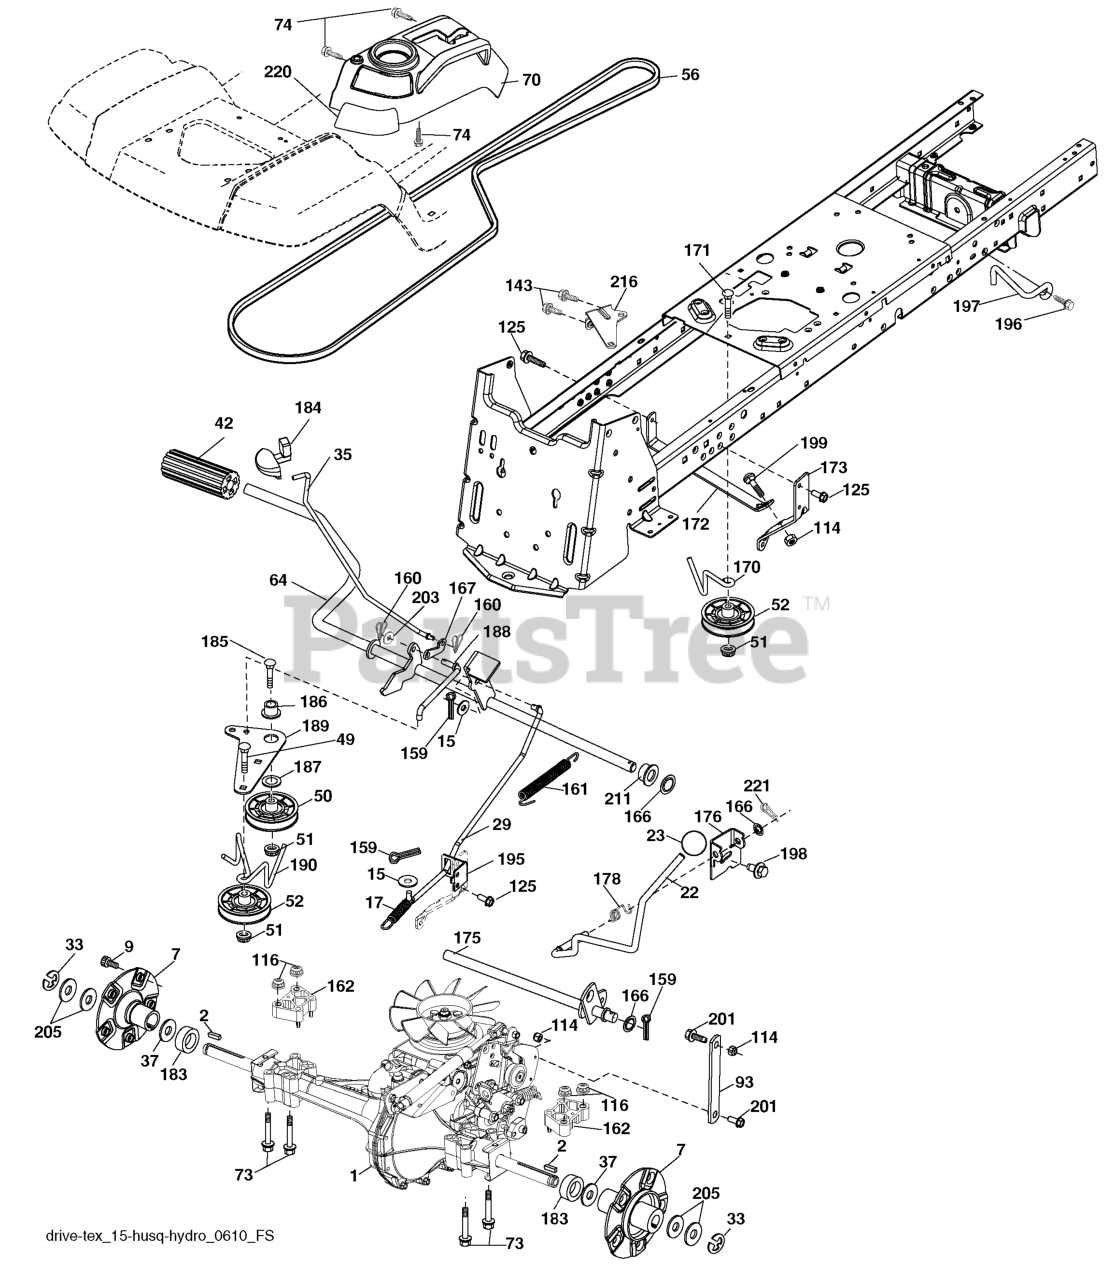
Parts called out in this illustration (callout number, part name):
2	KEY.SQUARE.187X2.500
7	HUB.ASM.WHEEL.REAR.22"
9	HUB BOLT
15	WASHER
17	SPRING.BRAKE.HG3000/3500
22	ROD.SHIFT.FENDER.STGT.
23	KNOB.DELUXE.(PISTOL.GRIP).BLAC
29	ROD.BRAKE.0610.PEDAL.CONTROL
35	ROD.BRAKE.PARKING.GT.H
42	PEDAL COVER T
49	BOLT
50	IDLER.FLAT.910.OFFSET
51	NUT LOCK FLG 3/8-16 UNC
52	IDLER.V-GROOVE.910.OFFSET
64	SHAFT.ASM.PEDAL.BRAKE.
70	RP CONSOLE.ASM.HYDO.HUSQ.
73	BOLT.HEX.FLNG.5/16-18X3.75
74	SCREW.HI-LO.CONSOLE
93	LINK.SHIFT.T/A.0610.TE
114	NUT.71038.31-18.HEX.NYLOCK
116	NUT LOCK HEX FLANGE 5/16-18
125	SCREW
143	Screw Thdrol 5/16-18 x 1/2
159	COTTER PIN
160	RETAINER CLIP
161	SPRING.RETURN.CLUTCH.2006
162	SPACER.TRANSAXLE.18&22
166	NUT.PUSH.625.2006
167	LATCH.BRAKE.SPRING
170	KEEPER.V-IDLER.CENTER.
171	BOLT
172	STRAP.TRQ.LH.FS.HG0510
173	STRAP.TORQUE.FS.0610.RH
175	SHAFT.ASM.SHFT.HG0510/
176	ARM.CLEVIS.ROD.SHIFT
178	SPRING.SHIFT.GT2006
183	SPACER.SPLIT.800X.350
184	HANDLE.PARKG.BRK.HUSQ X667
185	BOLT
186	SPACER.RETAINER
187	WASHER 12/32X2X10GA
188	RP.LINK.CLUTCH.GROUND.DRIVE
189	BELLCRANK.GROUND.DRIVE.TEX.
190	KEEPER.BELLCRANK.DRIVE
195	BRKT.ROD.BRAKE.18/20/2
196	SCREW 3/8-16X1
197	BRKT.ANIT-ROTATION.CLUTCH
198	SCREW.7/16-14X7/8.FLAN
199	BOLT
201	BOLT SHOULDER 5/16-18 UNC
203	WASHER
211	BUSHING.SHAFT.BRAKE.HAND
216	BRACKET.PULLEY.IDLER.W/TEX
220	REFLECTOR.RH.TEX GT
221	RETAINER.SPRING.CLIP.H
